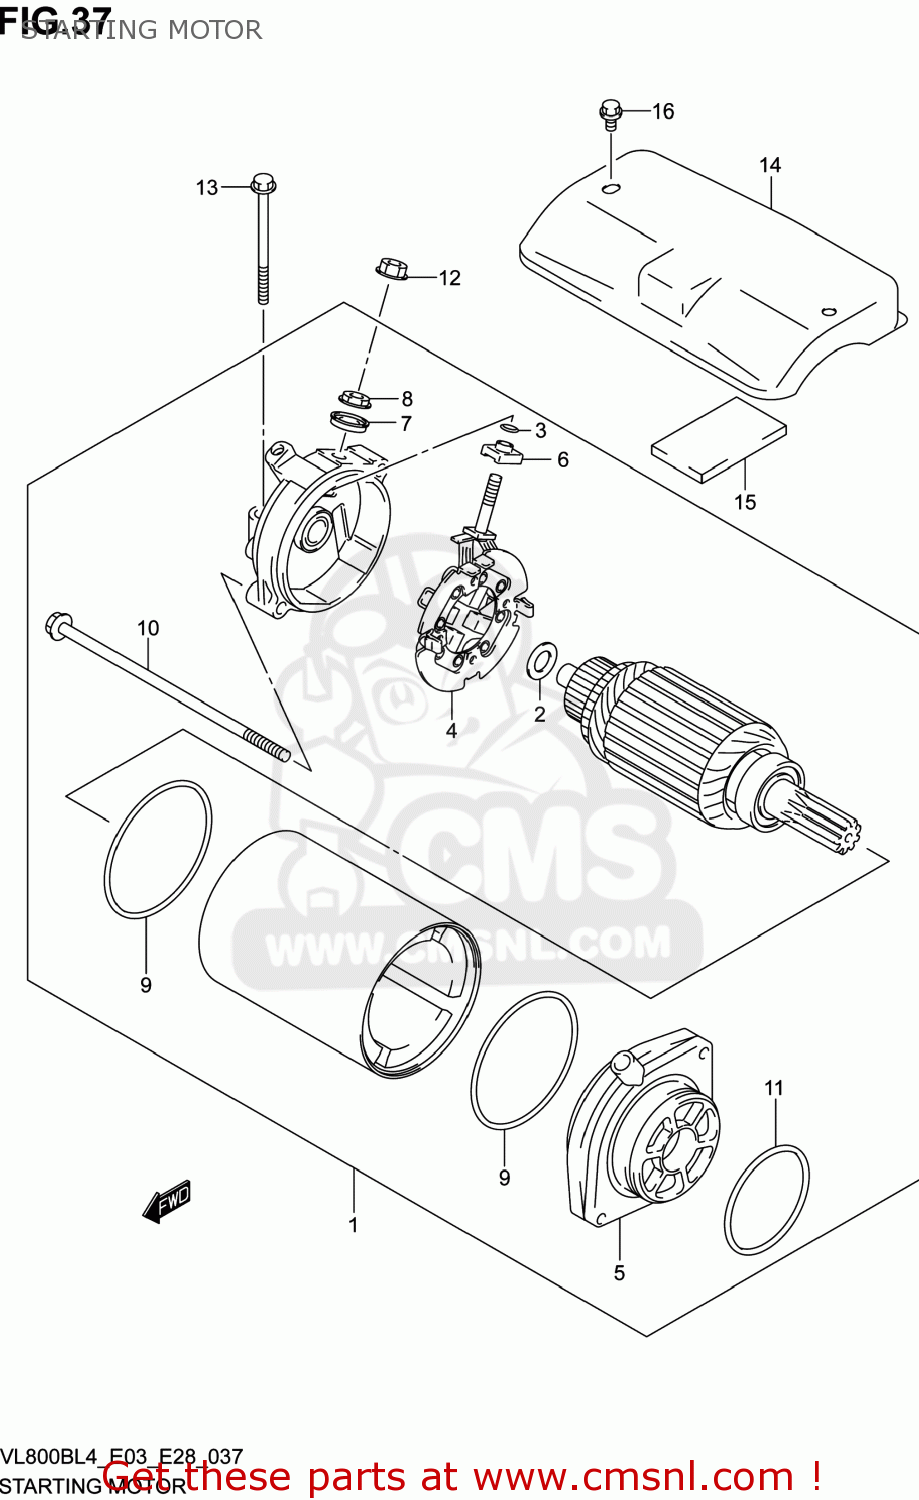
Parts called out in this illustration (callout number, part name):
1	MOTOR ASSY,STARTING
2	SHIM SET,STARTING MOTOR
3	O RING
4	HOLDER SET,BRUSH
5	BRACKET SET
6	BUSHING
7	BUSHING
8	NUT
9	O RING
10	BOLT
11	O RING
12	NUT
13	BOLT(6X60)
14	COVER,STARTING MOTOR
15	DAMPER,MOTOR COVER
16	BOLT
